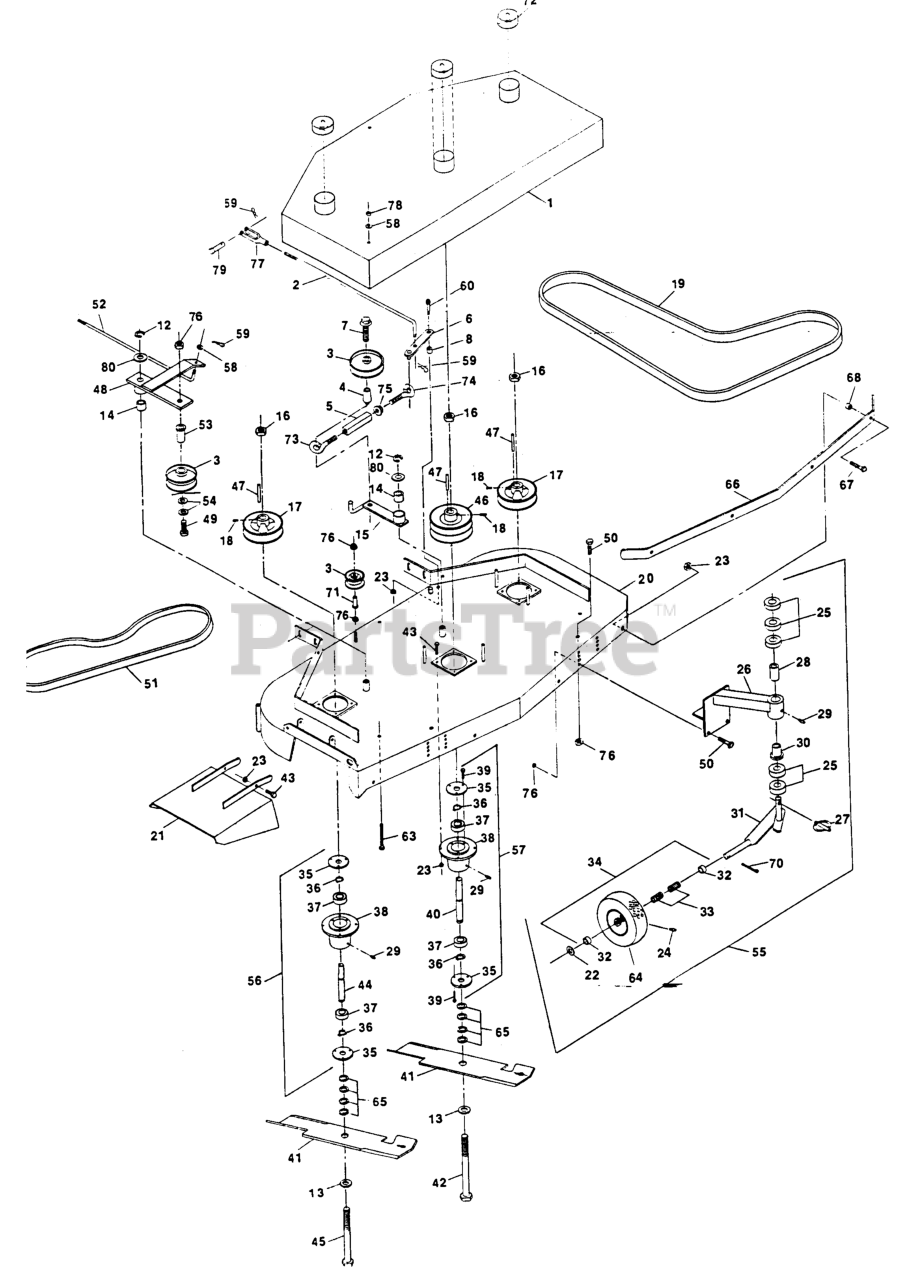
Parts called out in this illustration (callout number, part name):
5	BODY-TURNBUCKLE
14	BEARING,POWDERED METAL
17	PULLEY,CAST IRON
18	SCREW-SET
19	BELT,MAIN DECK
25	SPACER-CASTER
28	BEARING,STRAIGHT
31	WLD,CASTER STRUT
38	HOUSING,CUTTER
39	SCRWMACH PHS
42	SCREW-CAP, HH
44	SPINDLE,CUTTER
48	ARM,IDLER COMPLETE
51	BELT,FRONT DECK
52	ROD,BELT TENSION
56	HOUSING,CUTTER COMPLETE
57	HOUSING,CUTTER COMPLETE
59	PIN-COTTER
60	BOLT,SHLDR KSKH
63	BOLT,TAP HH
72	CAP,SPINDLE GUARD
73	EYEBOLT-THREAD, LH
74	EYEBOLT-THREAD, RH
77	YOKE-ADJUSTABLE
79	PIN-CLEVIS
80	WASHER-SPINDLE
